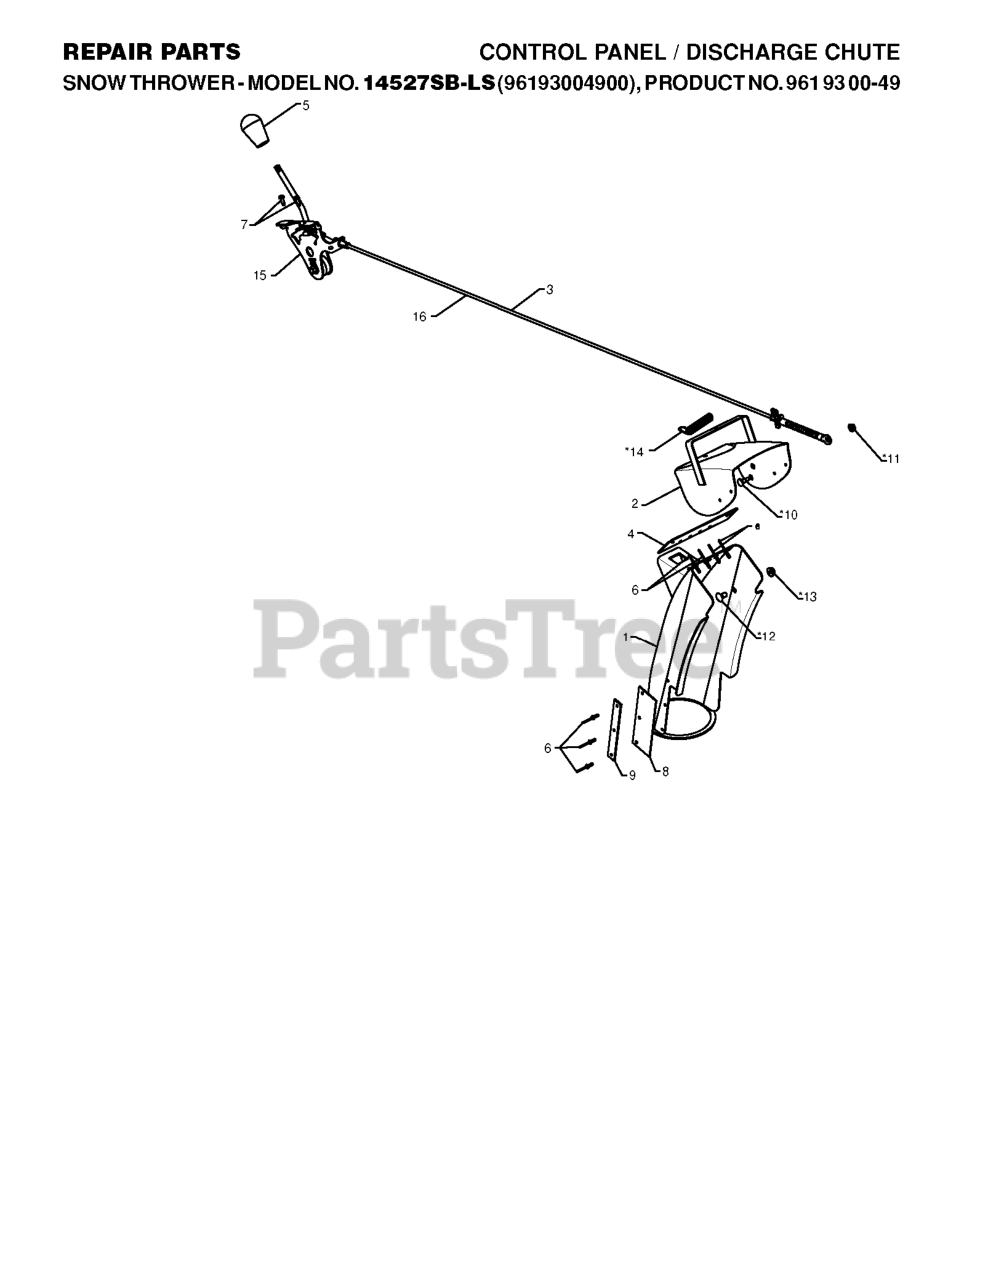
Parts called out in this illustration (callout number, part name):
1	RP CHUTE.WELDMENT.PNT.ORANGE
2	DEFLECTOR.WELDMENT.PNT.ORANGE
3	CONTROL.ASM.DEFLECTOR
4	SEAL.DEFLECTOR
5	KNOB LEVER, BLACK
6	RIVET BLIND
7	SCREW #10-24 X 5/8
8	RP STRAP.SHEILD.RETAINER
9	SHIELD.SNOW.CHUTE
10	BOLT, SHOULDER
11	NUT.HEX.FLANGE.1/4
12	BOLT
13	NUT.LOCK.5/16-18
14	SPRING.DEFLECTOR.REM.CHUTE
15	RP CNTRL.HEAD.ASSEM.DEFLECTOR
16	SERVICE.CHUTE.DEF.CBL.GRY
